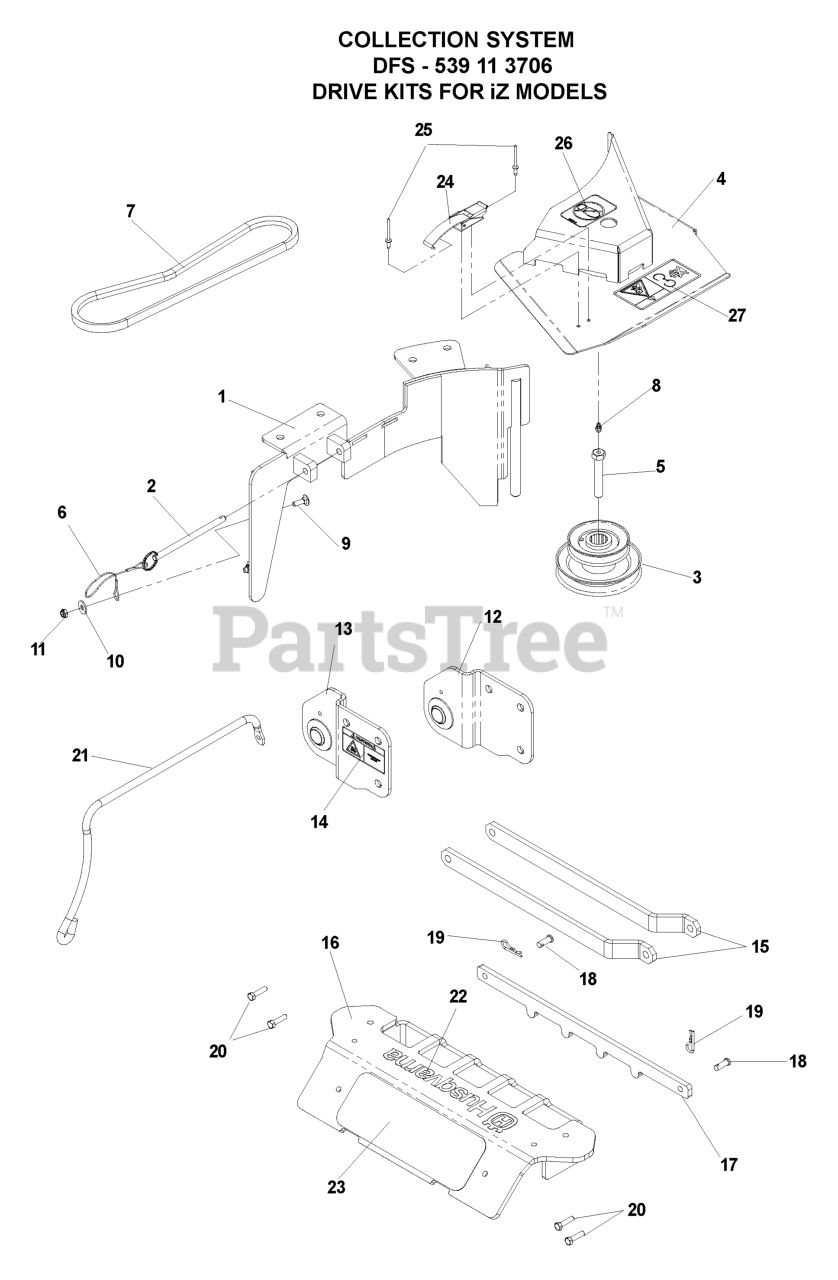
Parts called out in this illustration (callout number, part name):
1	BLOWER DECK PLATE, 48 DECK
1	BLOWER DECK PLATE, 52 DECK
1	BLOWER DECK PLATE, 61 DECK
3	STACK PULLEY, 48 DECK
3	STACK PULLEY, 52 DECK
3	STACK PULLEY, 61 DECK
4	BELT SHIELD, 48 DECK
4	BELT SHIELD, 52 DECK
4	BELT SHIELD, 61 DECK
5	HCS, 7/16-20 X 2 1/2, GR8
7	BELT, 48 DECK
7	BELT, 52 DECK
7	BELT, 61 DECK
8	ZERK
9	RHSNB, 1/4-20 X 3/4, GR2
10	WASHER, 1/4
11	NUT, 1/4-20, JAM, NYLOC
12	HITCH BRACKET, LEFT
13	HITCH BRACKET, RIGHT
14	DECAL, HOT SURFACE
16	WEIGHT BAR
17	HOLD DOWN, WEIGHT BAR
18	CLEVIS PIN
19	SPRING RETAINER
20	HCS, 5/16-18 X 1 1/4, GR5
21	HOSE SUPPORT
22	DECAL, HUSQVARNA
23	ABRASIVE PAD
24	DRAW LATCH
25	RIVET, BLIND, 5/32 DIA.
26	DECAL, NO STEP
27	DECAL, DANGER BELT DRIVES
539113706	Drive Kits (DFS)
